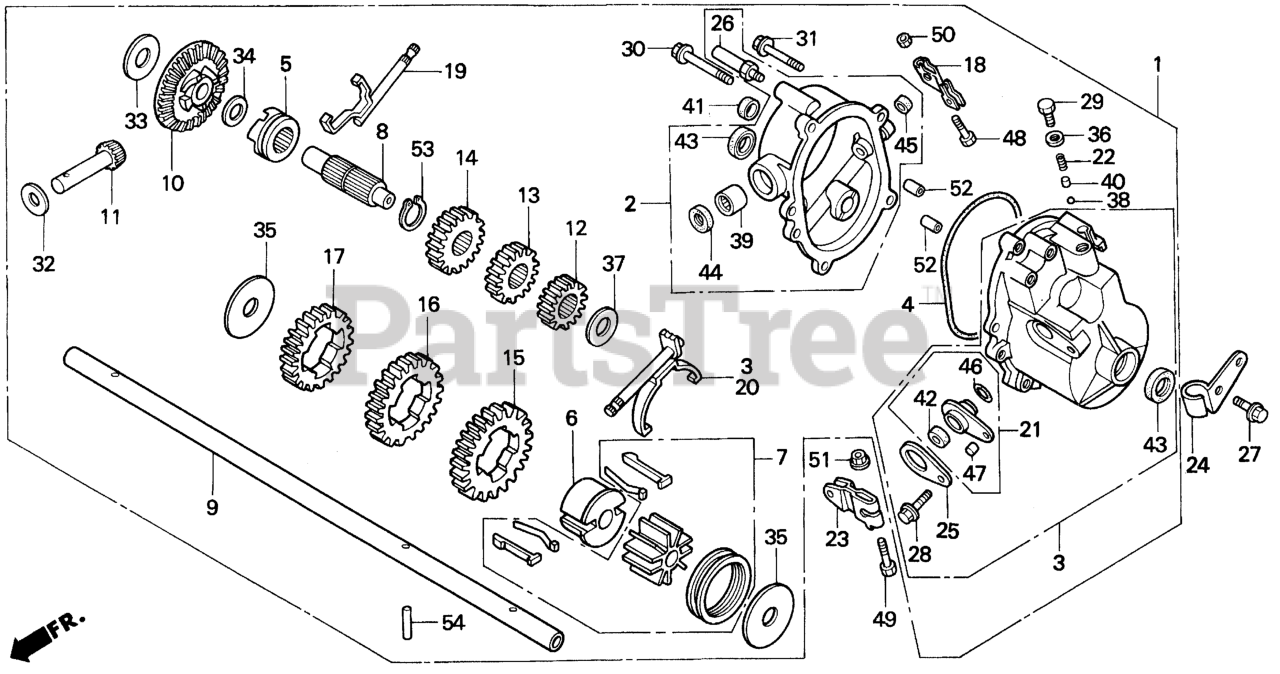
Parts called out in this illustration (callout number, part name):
1	TRANSMISSION ASSY. (DANA CORP.)
2	CASE ASSY., R. TRANSMISSION
3	CASE ASSY., L. TRANSMISSION
4	O-RING, TRANSMISSION CASE
4	O-RING, TRANS CASE
5	CLUTCH, DRIVEN
6	BOSS, CHANGE SHAFT
7	KEY & HOLDER ASSY.
8	COUNTERSHAFT
9	SHAFT, FINAL
10	GEAR, BEVEL (44T)
11	PINION, BEVEL
12	GEAR, FIRST DRIVE (14T)
13	GEAR, SECOND DRIVE (18T)
14	GEAR, THIRD DRIVE (20T)
15	GEAR, FIRST DRIVEN (33T)
16	GEAR, SECOND DRIVEN (29T)
17	GEAR, THIRD DRIVEN (27T)
18	ARM, CLUTCH
19	SHAFT, SHIFT
20	FORK, SHIFT
21	GUIDE ASSY., CHANGE LEVER
22	SPRING, BALL SET
23	ARM, CHANGE
24	BRACKET, WIRE HOLDER
25	HOLDER, SHIFT SHAFT
26	BOLT, GUIDE (8MM)
26	BOLT, GUIDE
27	BOLT, FLANGE (6X12) (CT200)
28	BOLT, FLANGE (6X16)
29	BOLT, HEX. (8X10)
30	BOLT, FLANGE (6X25)
31	BOLT, FLANGE (6X25)
32	WASHER (10X21)
33	WASHER, THRUST (14X32X1)
34	WASHER (14MM)
35	WASHER, THRUST (15X45)
36	WASHER, SEALING (8X16X1.6)
37	WASHER B, THRUST (12MM)
38	BALL, STEEL (6)
38	BALL, STEEL (#6) (3/16)
39	BEARING, NEEDLE (10X17X20)
40	RETAINER, BALL (6MM)
41	PLUG, SEALING (14X4)
42	OIL SEAL (8X16X6)
43	OIL SEAL (15X24X5)
44	OIL SEAL (10X17X4)
45	OIL SEAL (8X14X5)
46	O-RING (12.3X1.9)
47	COLLAR, FAN
48	BOLT, HEX. (5X20)
49	BOLT, HEX. (6X25)
50	NUT, HEX. (5MM)
51	NUT, FLANGE (6MM)
52	PIN A, DOWEL (8X14)
53	CIRCLIP (OUTER) (18MM)
54	ROLLER (6X22.4)
